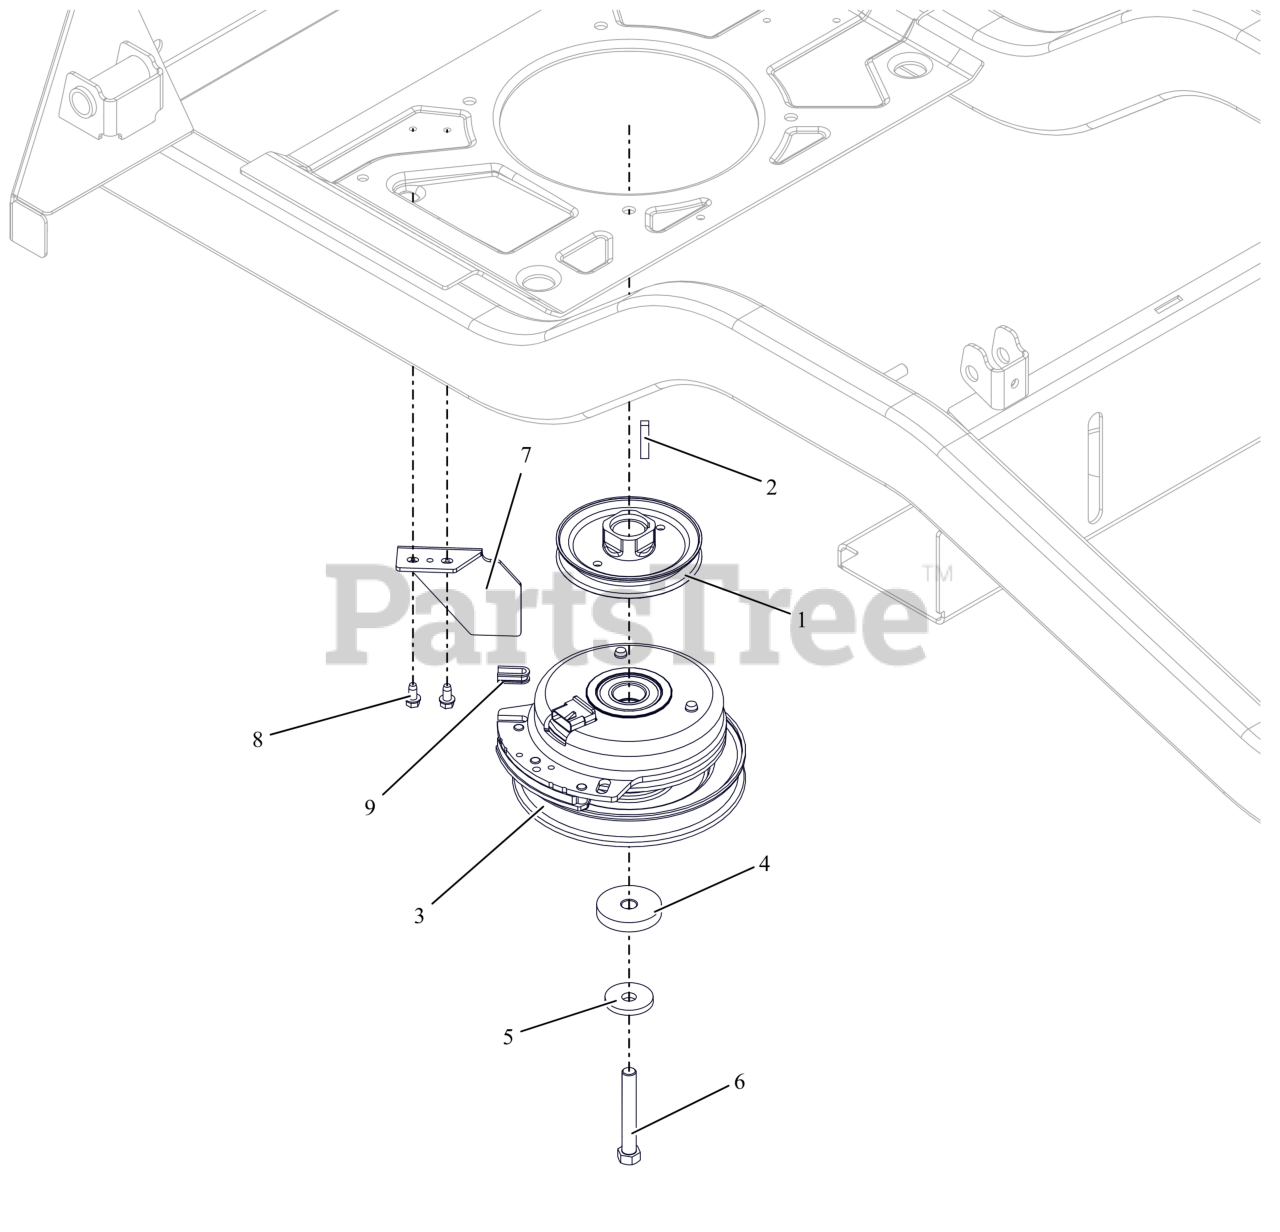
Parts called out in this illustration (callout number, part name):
1	WLDMT-PULLEY-4.50ODX1.003
2	KEY-SQ .25 X 1.25 X .25 SAE
3	CLUTCH- WARNER 1.00 HD-PTZ
4	SPACER, .474/.459X2.00X.350
5	WASHER, 7/16" SPRING DISK
6	BLT, HEX 0.4375-20X3 G8 ZCC NT
7	BRKT- CLUTCH STOP HD
8	SCR-TAP .25-20X.50 HWH ZCC
9	BSHG, CLUTCH
